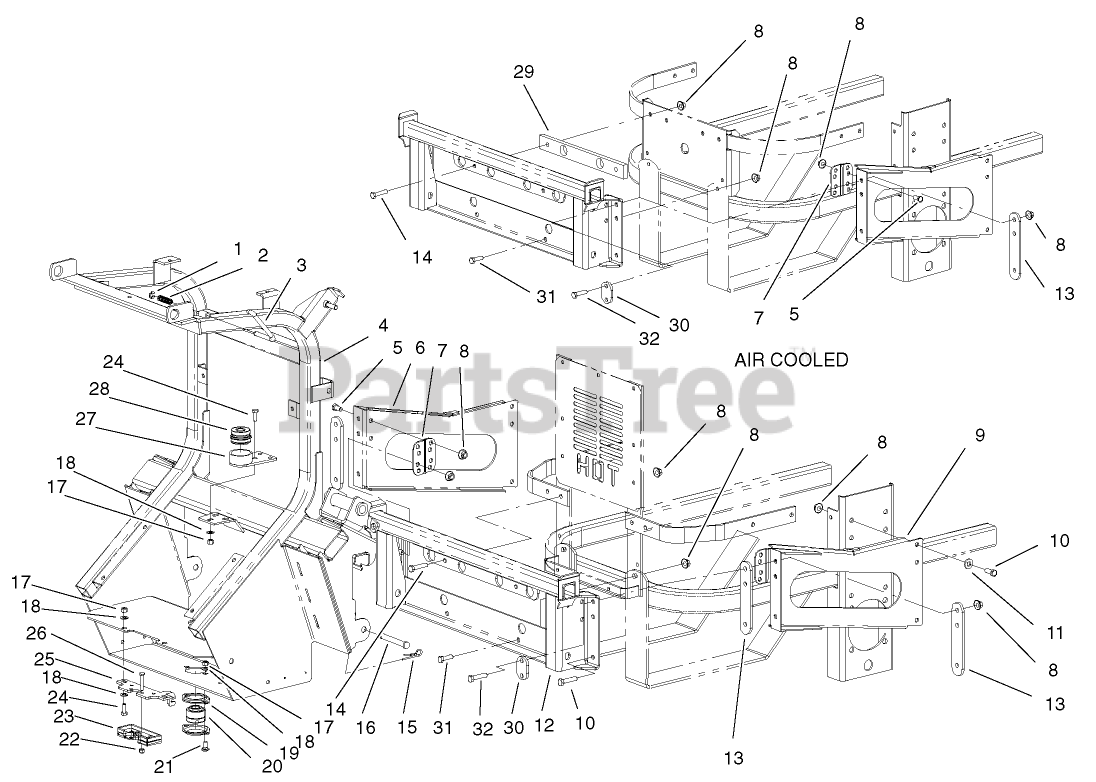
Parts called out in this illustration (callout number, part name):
2	SPRING
4	FRAME ASM
5	SCREW-HH
6	LH FRAME BRACKET ASM
7	BRACKET-STIFFENER
8	NUT-HF
9	RH FRAME BRACKET ASM
10	SCREW-HH
11	WASHER-BELLEVILLE
12	BAGGER MOUNT ASM
13	SPACER-FRAME
14	SCREW-HH
15	PIN-COTTER
16	PIN-CLEVIS
17	NUT-LOCK, NI
18	WASHER-PLAIN
19	FLANGE-BEARING
20	BEARING-SPHERICAL
21	BOLT-CARR
22	NUT-LOCK, NI
23	LATCH-ROTOR
24	SCREW-HH
25	BRACKET-LATCH
26	SCREW-HH
27	Bearing Flange ASM
28	BEARING-CYLINDRICAL
29	SPACER-FRAME, BAGGER
30	SPACER-FRAME, SHORT
31	SCREW-HH
32	SCREW-HH
